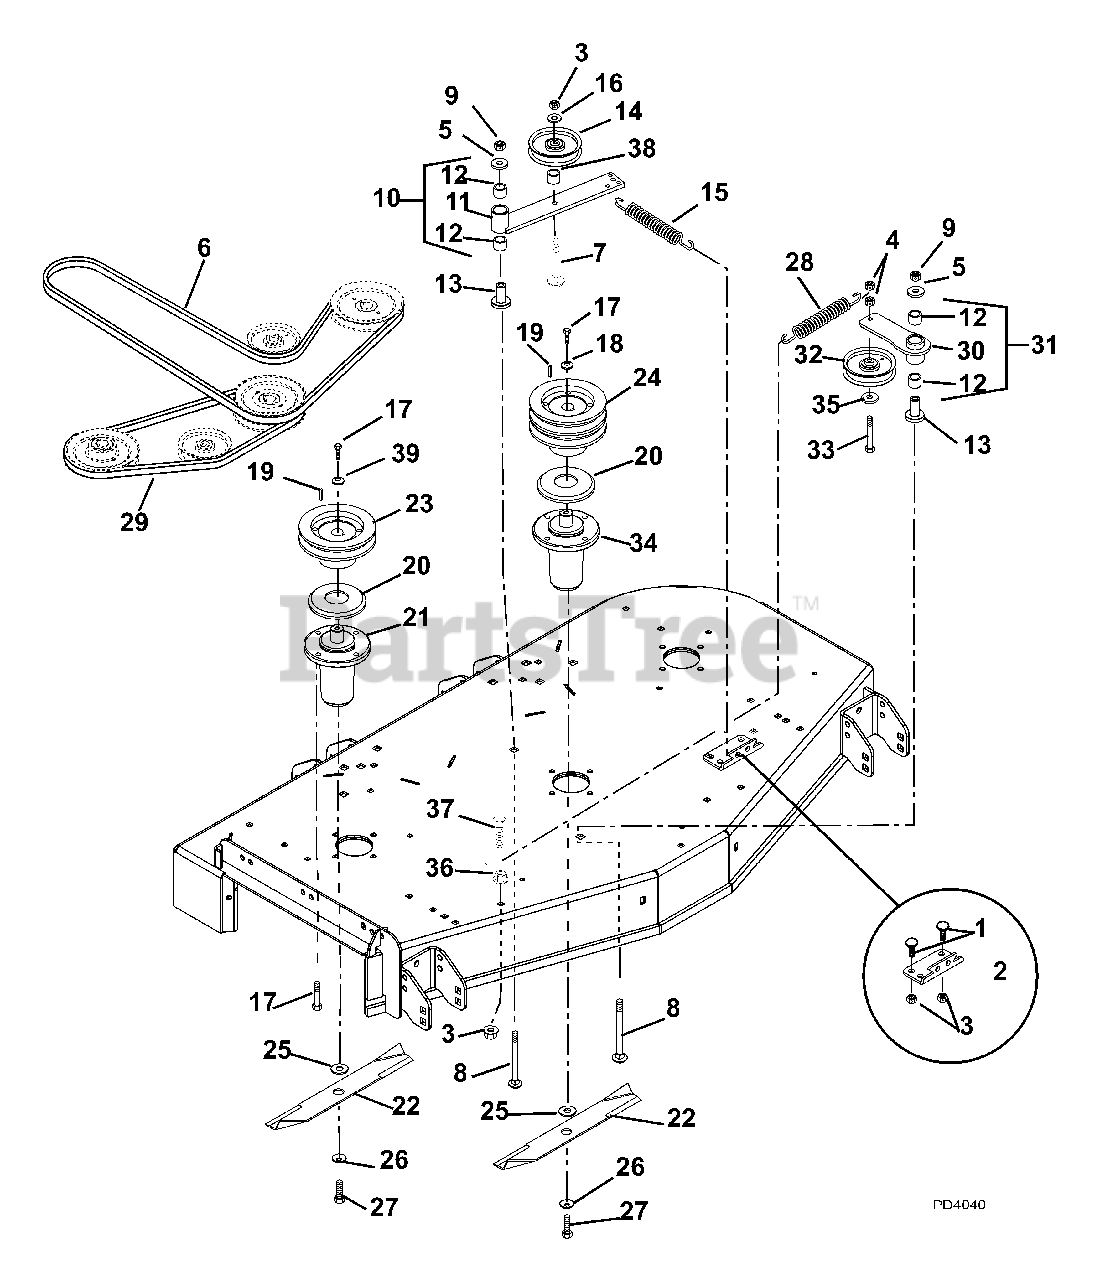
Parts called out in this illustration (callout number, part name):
1	Bolt, Round Head Square Neck .38-16 x .75 Grade 5
2	Bracket, Spring
3	Nut, Nyloc Flange 3/8-16
4	Nut, Locking Center .38-16
5	Washer, Flat Steel .531 x 1.25 x .10
6	V-Belt, B-RMA 52.38 x .625
7	Bolt-Round Head Square Neck .38-16 x 2.25 Grade 5
8	Bolt, Round Head Square Neck .50-13 x 3.50 Grade 5
9	Nut, Nyloc Flange .50-13
10	Assembly, Idler Pivot Arm
11	Weldment, Idler Pivot Arm
12	Bearing, 1.00 x 1.12 x .75
13	Bearing, Pedestal
14	Idler, Flat 4.00 x .38 (1.00 W)
15	Spring, Extension
16	Washer, Flat Steel .375 x 1.125 x .065
17	Bolt,Hex .38-16X1.00 EP30
18	Washer, Cupped Serrated .375
19	Key, Square .25 x .25 x 1.00 RC 40-50
20	Slinger, Dust
21	Assembly, Maintenance Free Spindle
22	Blade, Mower
23	Weldment, Spindle Sheave 5.00
24	Sheave, Double (5.25)
25	Washer, Flat .64 x 1.81 x .250
26	Washer, Bellville .63 x 1.625 x .14
27	Bolt, Hex .62-18 x 1.75 Grade 8
28	Spring, Extension
29	V-Belt, 5L-Section 49.97 x .672
30	Arm, Idler Pivot
31	Arm, Idler Pivot Arm
32	V-Idler, 4.00 x .38
33	Bolt, Hex .38-16 x 2.25 Grade 5
34	Spindle Assembly (Center)
35	Washer, Flat Steel .406 x .812 x .065
36	Nut-Flange .375-16
37	Bolt-Hex .38-16 x 3.50 Grade 5
38	Spacer .380 x .750 x .236
39	Washer, Flat Steel .406 x 1.50 x .245
